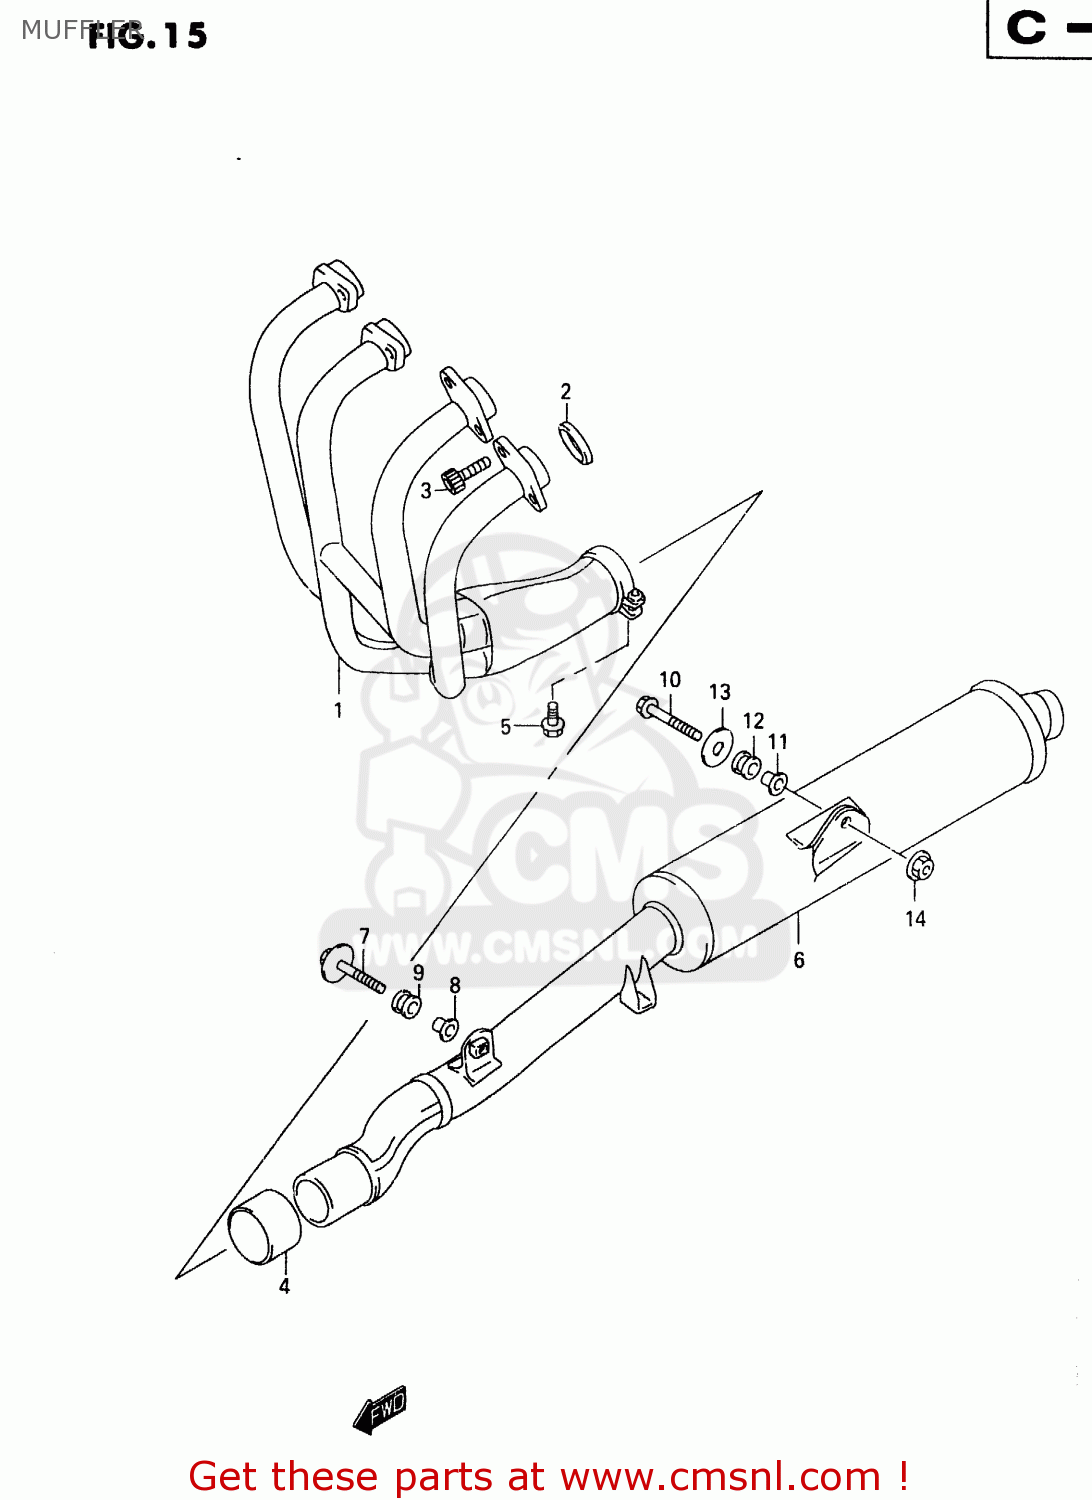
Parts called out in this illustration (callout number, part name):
1	EXHAUST COMP
2	GASKET,EXHAUST (NAS)
3	BOLT
4	CONNECTOR,MUFFLER
5	BOLT
6	BODY COMP,MUFFLER
7	BOLT 8X40
8	SPACER(8.6X12X24.2)
9	CUSHION
10	BOLT
11	SPACER(8.6X12X27.1)
12	CUSHION
13	WASHER (8.5X33X1.6)
14	NUT
